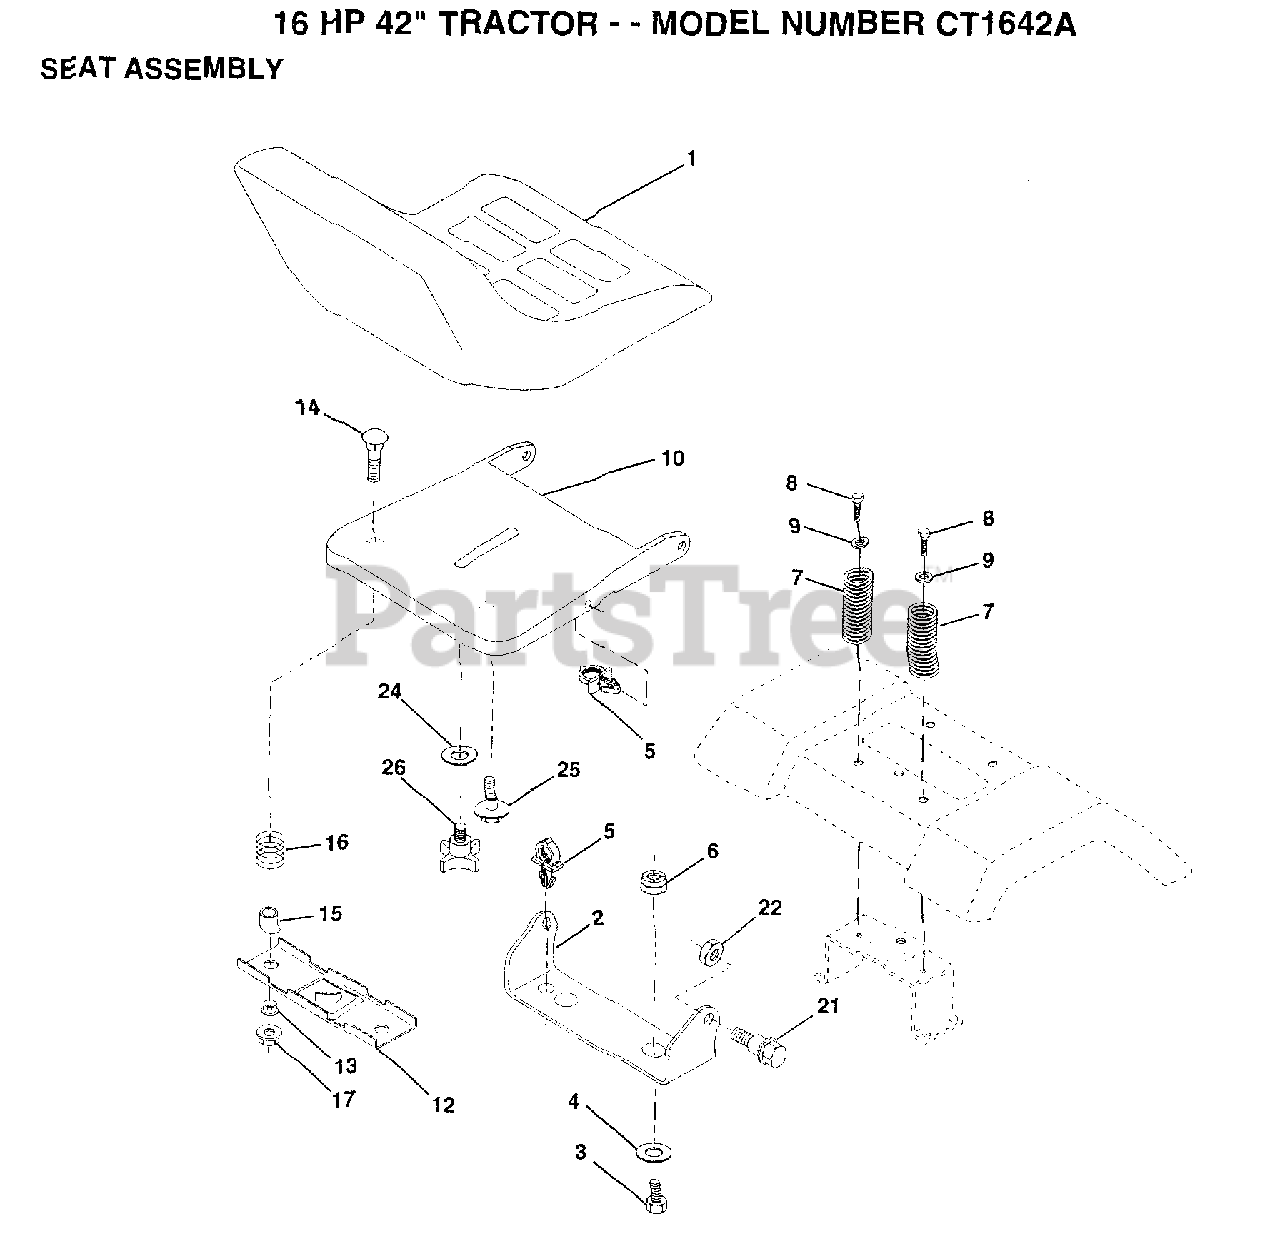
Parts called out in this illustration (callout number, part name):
2	BRACKET PVT SEAT
3	BOLT
4	WASHER PM
5	CLIP PUSH - IN
6	NUT
7	SPRING COMPRESSIO
8	SCREW GTV
9	WASHER
12	BRKT SWITCH
13	BUSHING
15	SPACER SPLIT
16	SPRING COMPRESSED
21	BOLT.SHLD.5/16-18
24	WASHER
25	"BOLT,SHOULDER"
26	"KNOB 1/2"" YT"
